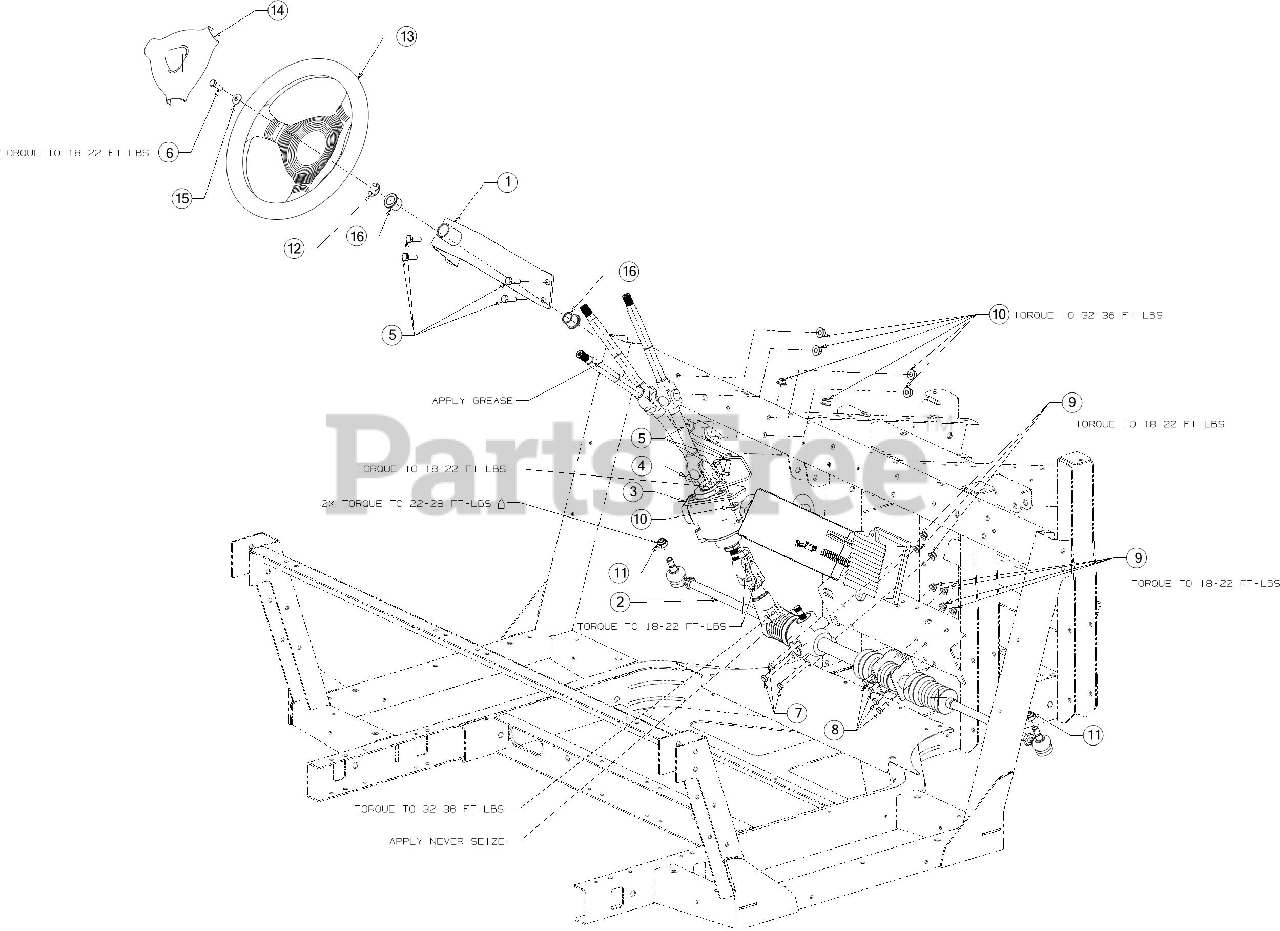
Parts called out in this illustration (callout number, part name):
1	STEERING WHEEL SUPPORT ASSEMBLY
2	STEERING ASSEMBLY
3	EPS STEERING ASSEMBLY
4	EPS MOUNT BRACKET
5	SCREW 3/8-16 x 1 GR5
6	SCREW 5/16-18 x 1.00 GR5
7	SCREW 5/16-18X3.5 GR5
8	SCREW 5/16-18 x .75 GR5
9	FLANGE LOCK NUT 5/16-18
12	E-RING
13	STEERING WHEEL 3-SPOKE
14	STEERING WHEEL COVER
15	BELL WASHER .337 X.867 x .057
16	FLANGE BEARING
